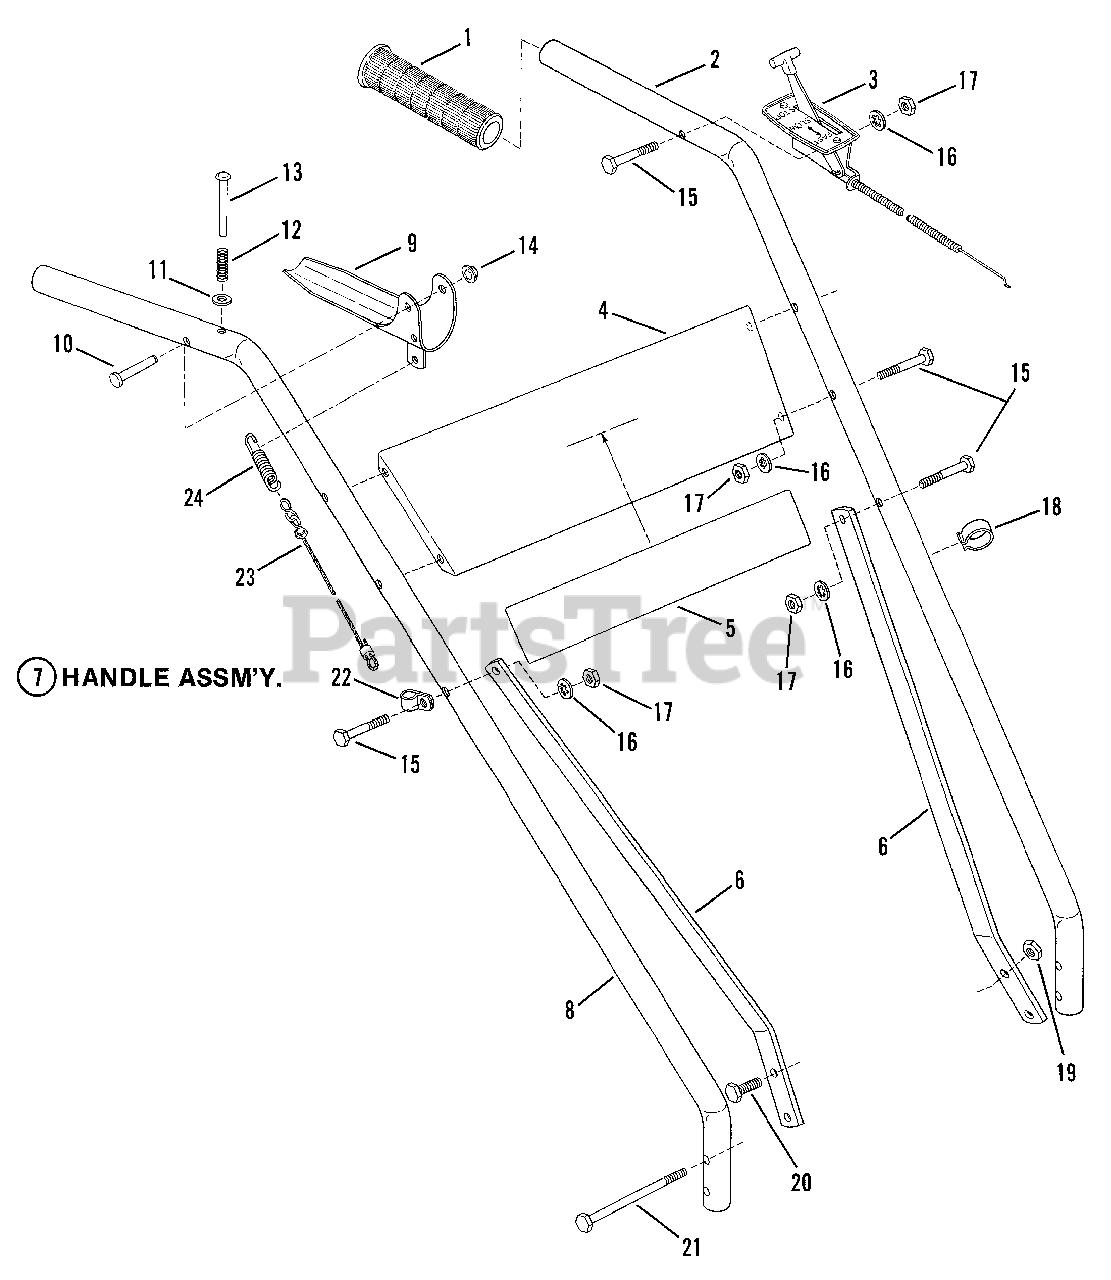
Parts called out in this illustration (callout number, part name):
1	GRIP, Handle
2	HANDLE BAR, Left Hand
3	CONTROL, Throttle
4	BRACE, Cross
5	DECAL, SNAPPER
6	TIE-BAR
7	ASSM'Y., Handle
8	HANDLE BAR, Right Hand
9	LEVER, Clutch
10	PIN
11	(NLA) WASHER, 1/4 Flat
12	(NLA) SPRING
13	(NLA) PIN
14	NUT, Push
15	SCREW, 1/4-28x1-3/4" Hex Hd. Cap
16	WASHER, 1/4 Internal Tooth
17	NUT, 1/4-28
18	CLIP, Throttle Control
19	NUT, 5/16-24 Hex Lock
20	SCREW, 5/16-24x1" Hex Hd. Cap
21	SCREW, 5/16-24x4" Hex Hd. Cap
22	GUIDE, Cable
23	CABLE, Clutch Assm'y.
24	SPRING, Clutch Cable
